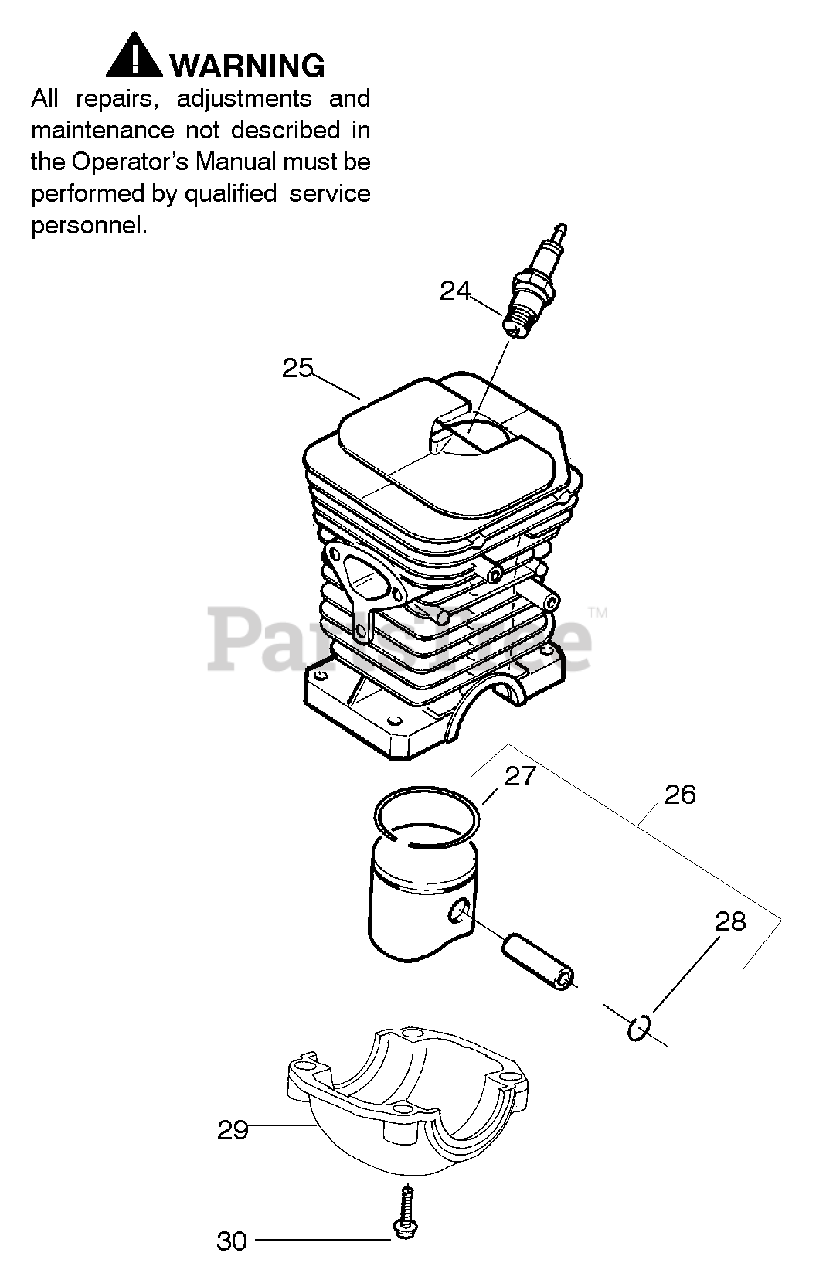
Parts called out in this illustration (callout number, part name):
24	Spark Plug (RCJ-7Y)
25	Kit-Cylinder (36cc)
26	Kit-Piston (36cc)
27	Ring-Piston (36cc)
28	Piston Pin Retainer
29	Cap-Crankcase
